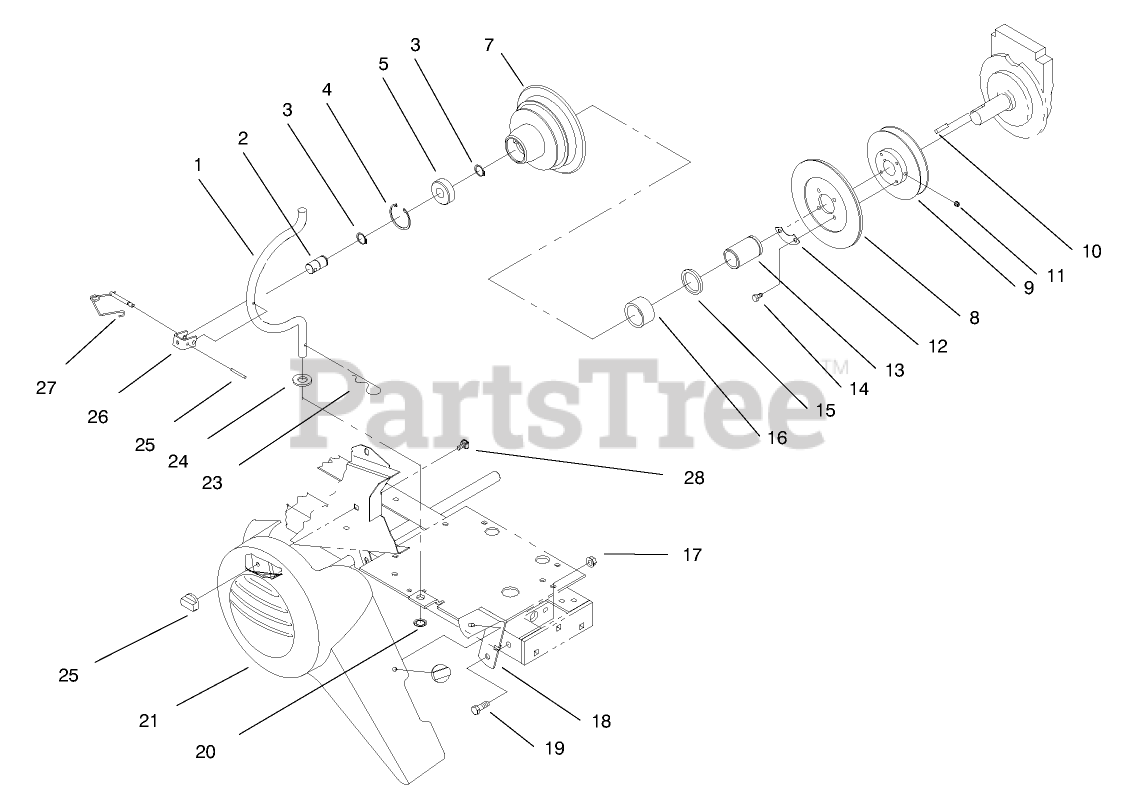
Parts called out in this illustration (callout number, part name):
1	ROD-HOUSING
2	SHAFT-PTO
3	RING-SNAP
4	RING-RETAINING
5	BEARING-BALL
8	ASS'Y-CLUTCH PLATE
9	PULLEY
11	SCREW-SET, HSH
12	RETAINER
13	RACE-BEARING
15	SEAL-OIL
17	NUT-FLANGE
18	Bracket
19	SCREW-HH
20	RING-REINFORCED CIRC
21	GUARD - BELT
22	NUT - WING
23	PIN-COTTER, HAIR
24	WASHER-FLAT
25	PIN-ROLL
26	CLEVIS
27	LOCKING PIN ASM
